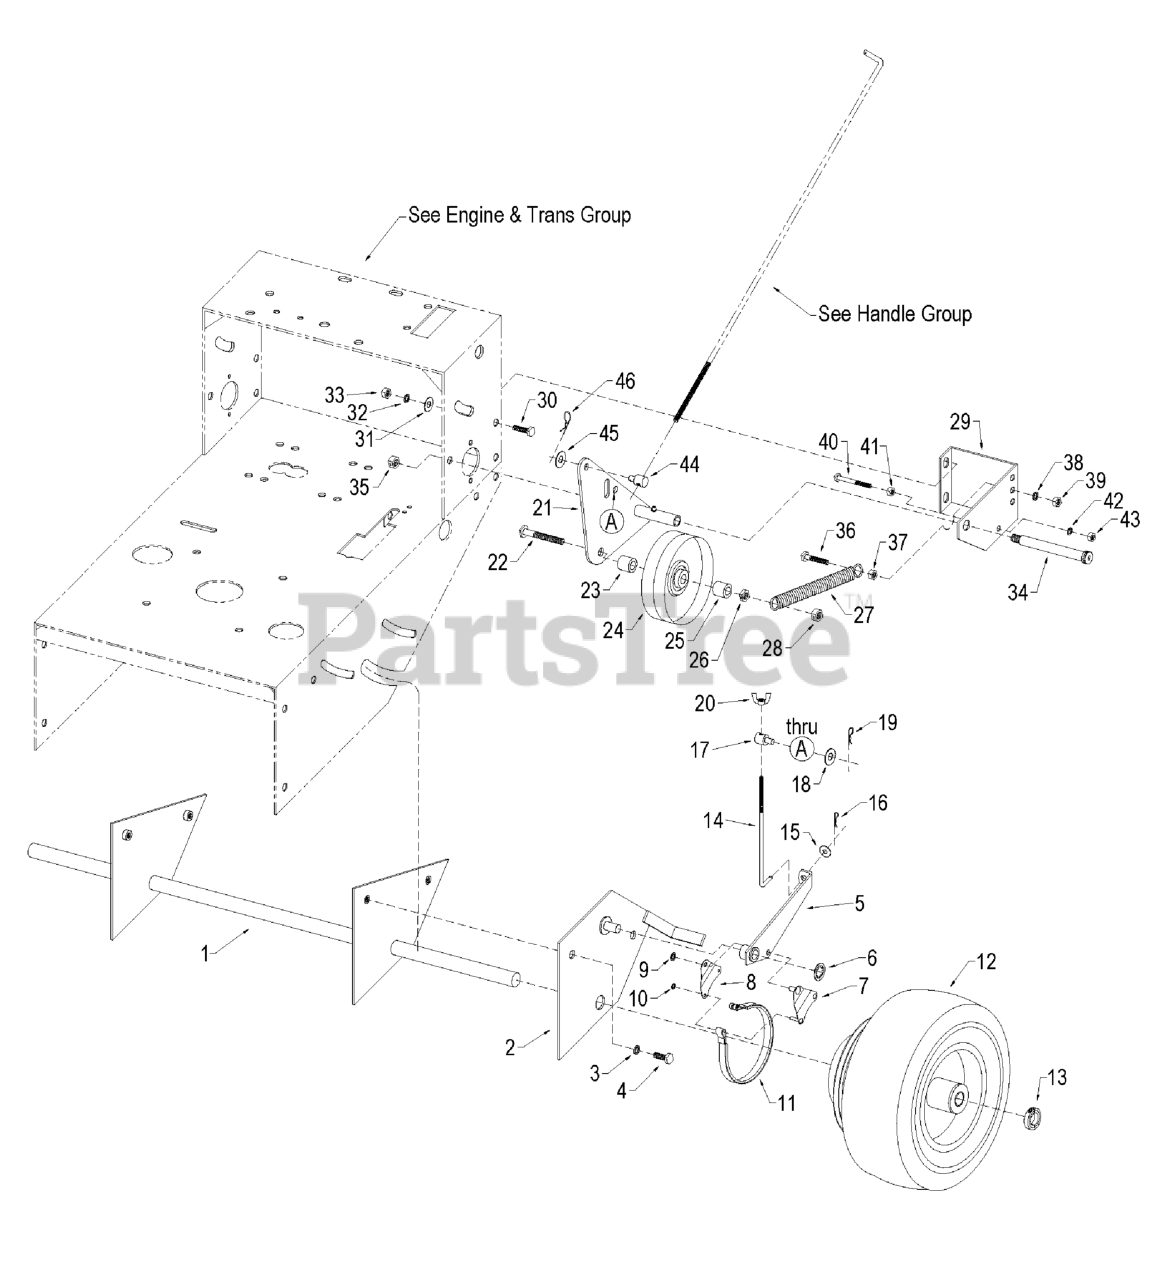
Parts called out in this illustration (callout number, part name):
1	Axle assembly
2	Brake pivot plate - left
3	BOLT, 3/8-16 x 1
4	WASHER, 3/8" Lock
5	Brake arm - left
6	5/8" retaining washer
7	Brake link plate w/pins
8	Brake link plate - no pins
9	3/8" push-on washer
10	5/16" push-on washer
11	Brake band
12	13-5.00 x 6 wheel & tire assy
13	COLLAR, 1" Split
14	Lower brake rod
15	WASHER, 5/16" SAE
16	#2 bridge pin
17	Rod fitting end - unthreaded
18	WASHER, 5/16" SAE
19	#2 bridge pin
20	NUT, 5/16-18, Wing Nylon Lock
21	Side idler plate - left
22	BOLT, 1/2-13 X 3-1/2, HEX HD, GD5, CZ (SV)
23	1/2" id x 5/8" spacer
24	Side idler pulley
25	1/2" id x 3/8" spacer
26	NUT, 1/2-13 HEX NYLON LOCK
27	Side idler tension spring
28	NUT, 1/2-13 HEX NYLON LOCK
29	Side idler spring bracket - left
30	BOLT, 3/8-16 X 1" GD5 CZ
31	WASHER, 3/8 SAE
32	WASHER, 3/8" Lock
33	NUT, 3/8-16 Hex
34	SHOULDER BOLT, 5/8 x 4-1/4
35	NUT, 1/2-13 HEX NYLON LOCK
36	BOLT, 3/8-16 X 1-1/2" GD5 CZ
37	NUT, 3/8-16 Hex
38	WASHER, 3/8" Lock
39	NUT, 3/8-16 Hex
40	BOLT, 5/16-18 x 3
41	NUT, 5/16-18 HEX
42	WASHER, 5/16 LOCK CZ
43	NUT, 5/16-18 HEX
44	Rod fitting end (trunion)
45	WASHER, 5/16" SAE
46	#2 bridge pin
